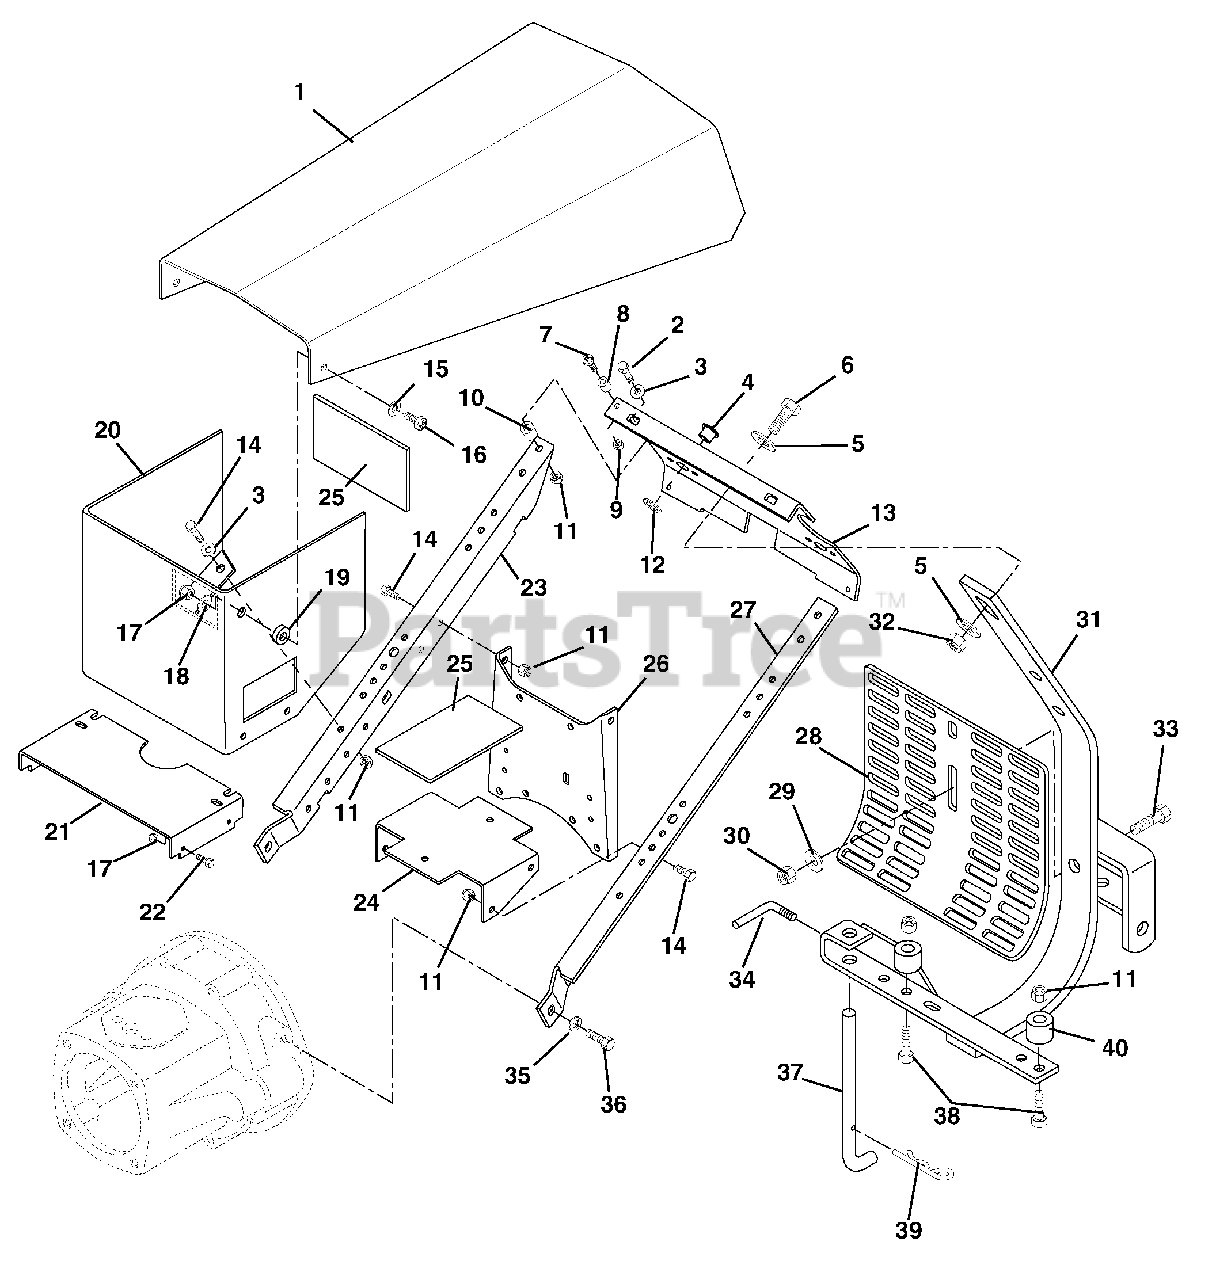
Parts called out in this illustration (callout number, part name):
1	Hood 8 HP
2	Bolt-Hex .38-16 x 1.50 Grade 5
3	Washer-Flat-Steel .406 x .812 x .065
4	Bushing-Flange .515 x .750 x .745 x 1.00
5	Washer-Flat-Steel .656 x 1.31 x .095
6	Bolt-Hex .625-11 x 2.00
7	Screw-Machine 6-32 x .75
8	Bumper
9	Nut-Locking-Nylon 6-32
10	Bushing
11	Nut-Locking-Center .375-16 Grade 2
12	Ring-Retaining 1.000 x .748
13	Plate, Instrument-Briggs Engine
13	Plate, Instrument-Robin and Kohler Engines
14	Bolt-Hex .38-16 x .75
15	Washer-Flat-Steel .281 x .620 x .065
16	Screw-Machine .25-20 x 1
17	Nut-Locking-Center .25-20 Grade 2
18	Washer-Flat-Steel .38 x .875 x .085
19	Bushing, Flange .280 x .750 x .318
20	Support, Hood
21	Bracket, Battery Mount
22	Bolt-Hex .25-20 x .63
23	Support, Handle Bar Right Hand
24	Bracket, Tank Support
25	Pad, Gas Tank
26	Bracket
27	Support, Handle Bar Left Hand
28	Guard, Engine
29	Washer-Flat-Steel .563 x 1.30 x .109
30	Nut-Locking-Center .50-13 Grade 5
31	Weldment, Hitch
32	Nut-Locking-Center .625-11 Grade 2
33	Bolt-Hex .50-13 x 1.50 Grade 5
34	Handle, Adjusting
35	Washer-Lock .50 x .125 Reg.
36	Bolt-Hex .50-13 x 1 Grade 5
37	Stand, Kick
38	Bolt-Hex .38-16 x 2.00 Grade 5 (114)
38	Bolt-Hex .38-16 x 2.50 Grade 5 (115, 117, 119, 307, 309, 311-313)
39	Pin-Hair-Internal .15 x 2.937
40	Spacer
